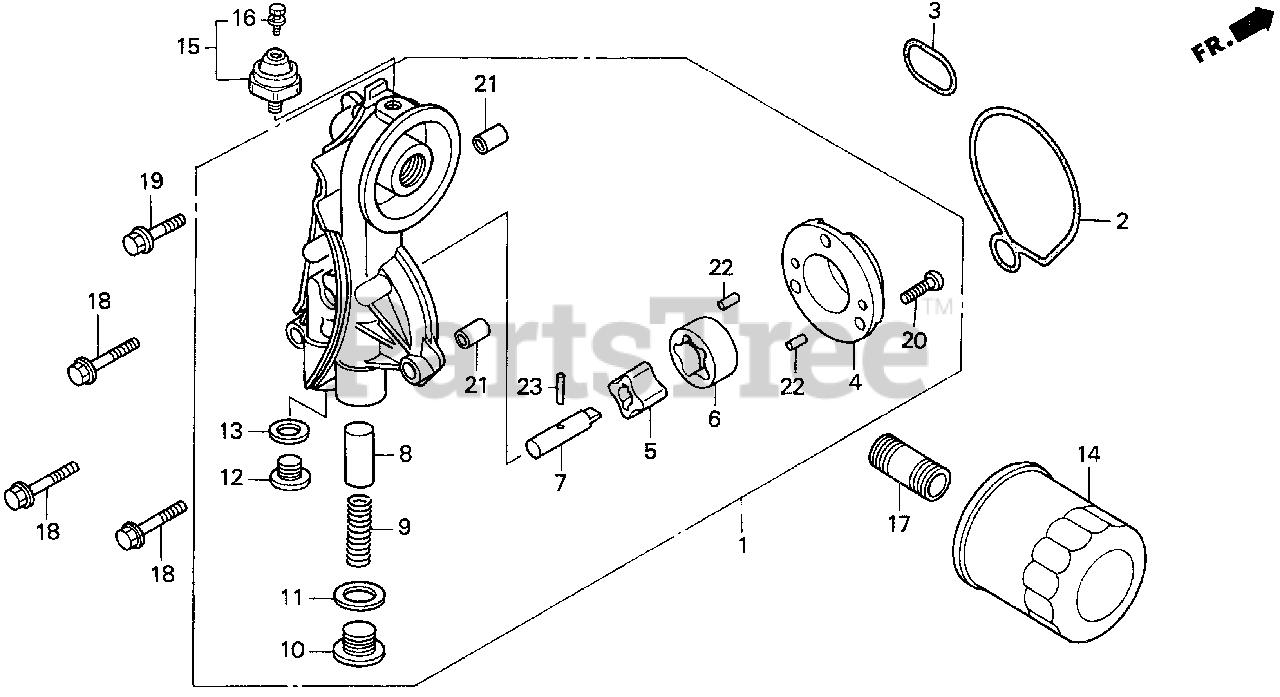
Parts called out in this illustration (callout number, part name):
1	PUMP ASSY., OIL
2	GASKET, OIL PUMP
3	GASKET, OIL PUMP (B)
4	COVER, OIL PUMP
5	ROTOR, OIL PUMP (INNER)
6	ROTOR, OIL PUMP (OUTER)
7	SHAFT, OIL PUMP
8	VALVE, RELIEF
9	SPRING, RELIEF VALVE
10	BOLT, SEALING (18MM)
11	WASHER, SEALING (18MM)
12	BOLT, SEALING (14MM)
13	WASHER, SEALING (14MM)
14	FILTER, OIL
14	FILTER, OIL (DENSO)
15	SWITCH, OIL PRESSURE
16	SCREW-WASHER (4X8)
17	HOLDER, OIL FILTER
18	BOLT, FLANGE (6X32)
19	BOLT, FLANGE (6X25)
20	SCREW, PAN (6X14)
21	PIN A, DOWEL (8X14)
22	PIN, DOWEL (5X8)
23	ROLLER (3X15.8)
